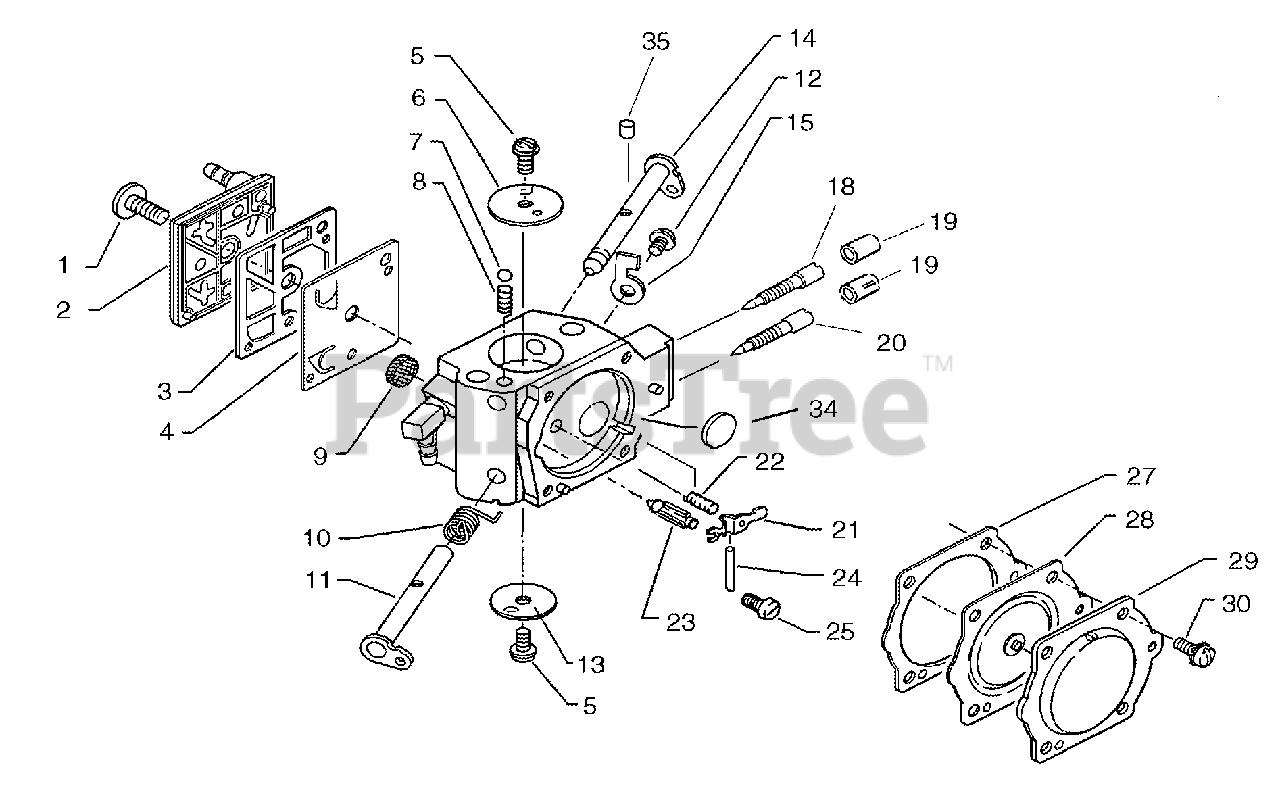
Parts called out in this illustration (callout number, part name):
2	COVER, FUEL PUMP
3	GASKET, FUEL PUMP
4	DIAPHRAGM, FUEL PUMP
6	VALVE, CHOKE
7	BALL, CHOKE FRICTION
9	SCREEN, FUEL INLET
10	SPRING, THROTTLE RETURN
11	SHAFT, THROTTLE
13	VALVE, THROTTLE
14	SHAFT, CHOKE
15	STOP, THROTTLE
18	NEEDLE, HIGH SPEED
19	CAP, LIMITER
20	NEEDLE, MIXTURE
21	LEVER, METERING
23	VALVE, INLET NEEDLE
24	PIN, METERING LEVER
25	SCREW, METERING LEVER PIN
27	GASKET, METERING DIAPHRAGM
28	DIAPHRAGM, METERING
29	COVER, METERING DIAPHRAGM
34	PLUG, WELCH
35	PLUG, FRICTION
